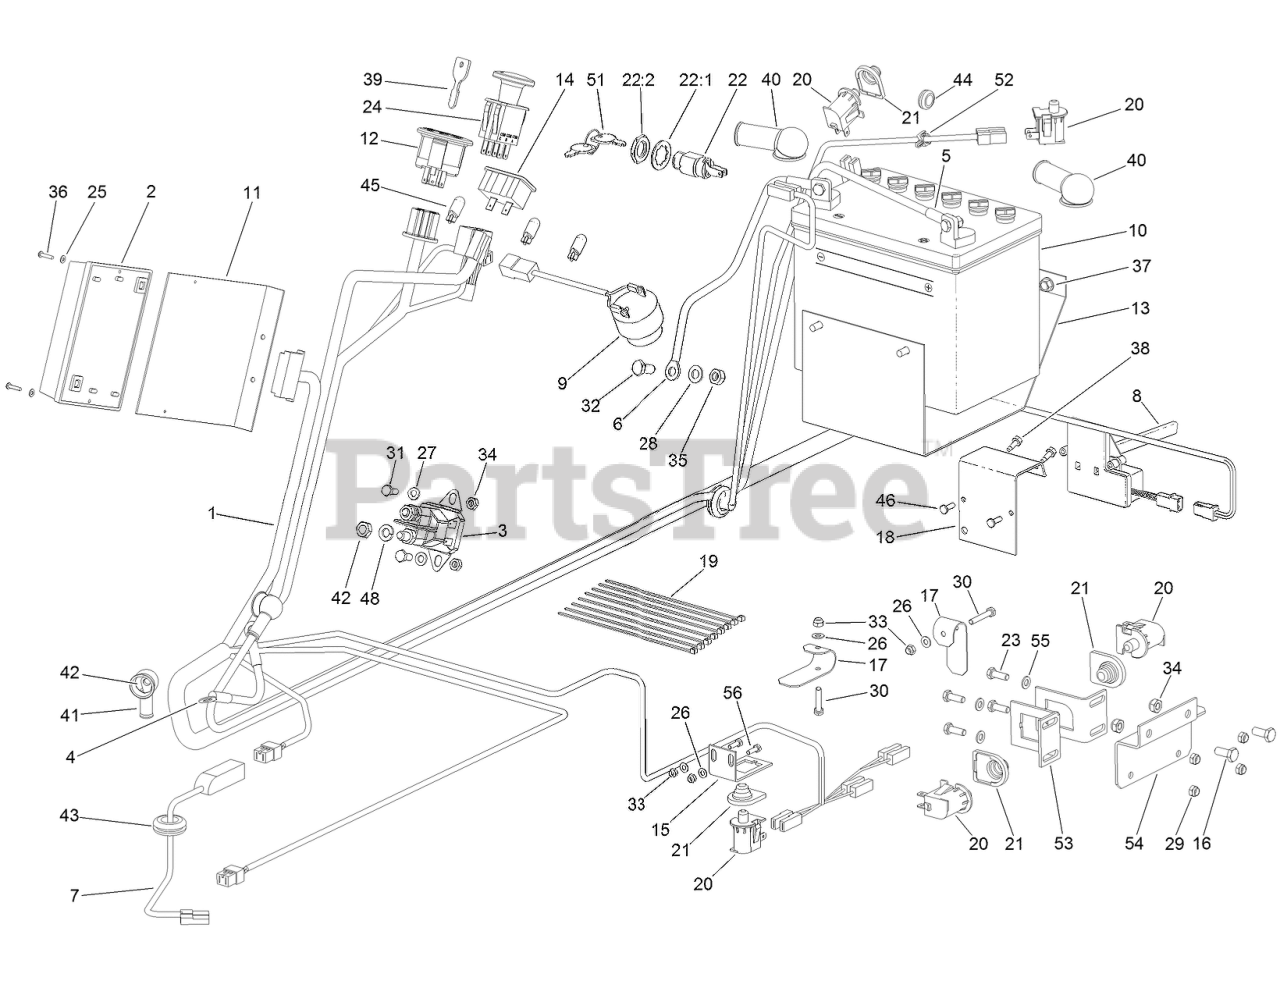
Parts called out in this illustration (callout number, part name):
1	HARNESS-WIRING
2	CONTROL MODULE
3	SOLENOID
4	CABLE-STARTER
5	CABLE-BATTERY, POSITIVE
6	CABLE-BATTERY, NEGATIVE
7	HARNESS-CLUTCH
8	OVERLOAD SWITCH ASM
9	BUZZER
10	BATTERY-12V
11	HOLDER-MODULE
12	SWITCH-IGNITION
13	HOLDER-BATTERY
14	HOURMETER
15	HOLDER
17	LEVER-SPRING
18	BRACKET-SWITCH
19	TIE-CABLE
20	SWITCH-DELTA
21	COVER-PROTECTIVE
22	STARTER SWITCH ASM
22:1	WASHER-TOOTH, INTERNAL
22:2	NUT-HH
24	SWITCH-PTO
25	WASHER
26	WASHER
27	WASHER
28	WASHER-PLAIN
29	NUT-LOCK
30	SCREW-HEX
31	SCREW-HH
32	SCREW-HH
33	NUT-HEX
34	NUT-LOCK
35	NUT-LOCK, NI
38	SCREW-TAP
39	KEY-IGNITION
40	BOOT-RUBBER
41	BOOT-RUBBER
42	NUT-HHF
43	BUSHING
44	BUSHING
46	Screw
48	WASHER-SPRING
51	KEY-IGNITION
52	CLIP-SNAP
53	HOLDER-SWITCH
54	HOLDER-SWITCH
55	WASHER
